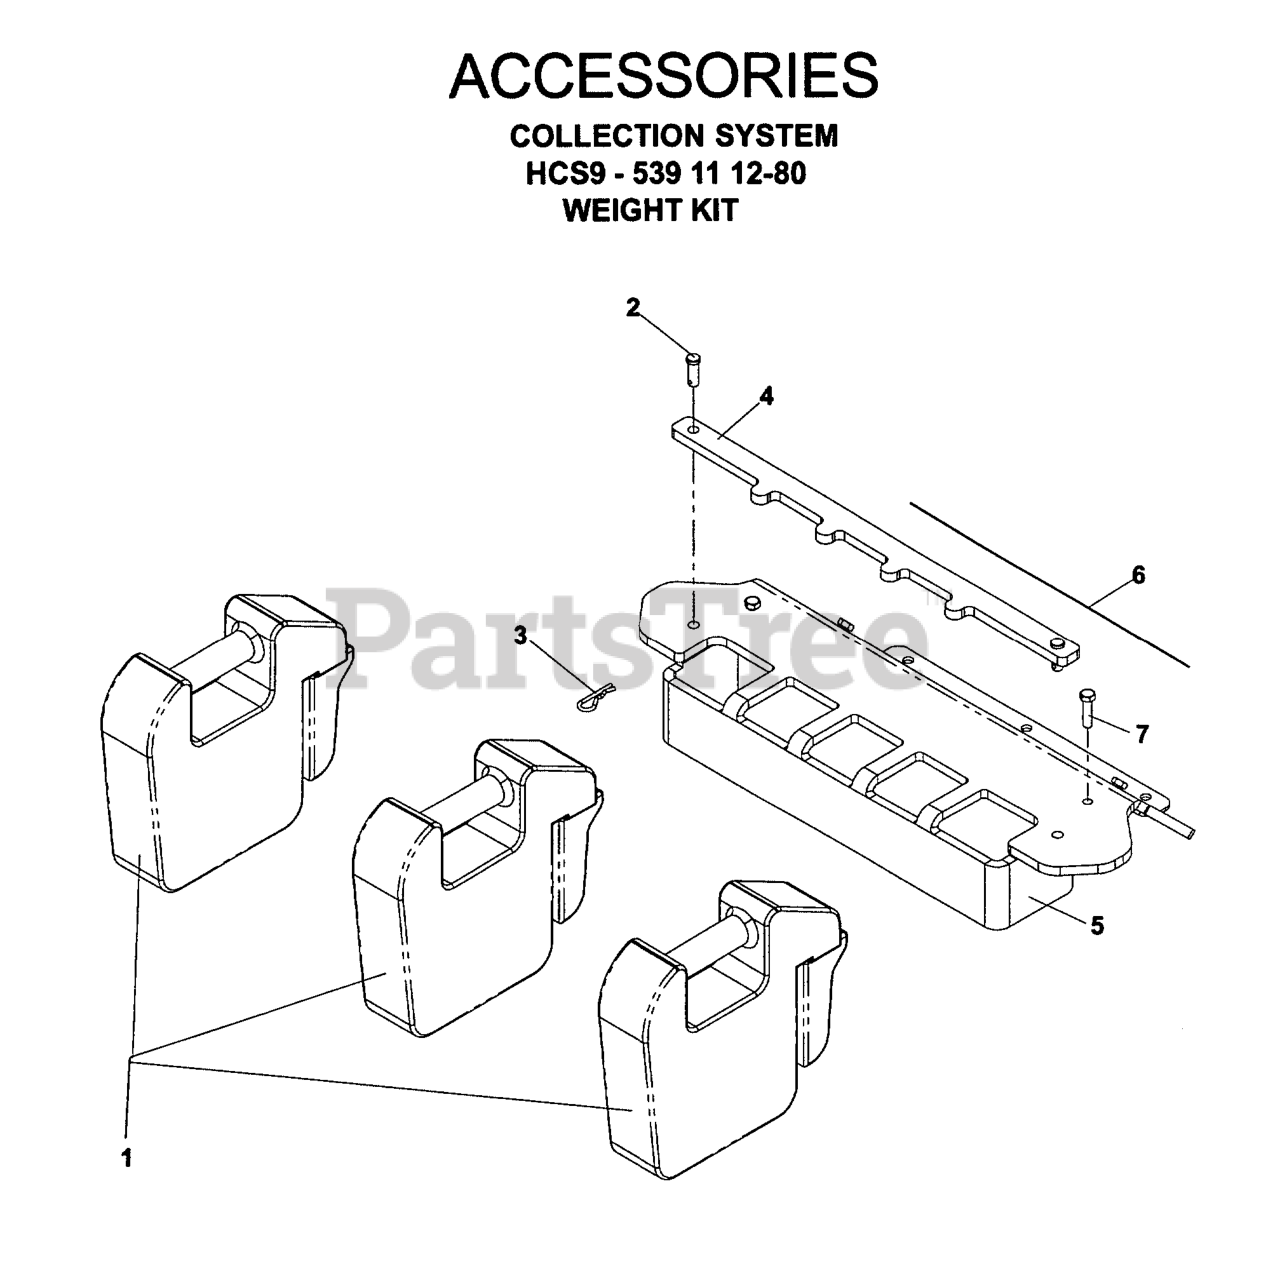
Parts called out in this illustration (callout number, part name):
1	FRT WEIGHT CAST PZ DFS
2	CLEVIS PIN
3	RETAINER SPRING
4	HOLD DOWN, WEIGHT BAR
5	WEIGHT BAR, IZ
6	ANTI-SKID PAD
7	HCS 5/16C X 1 1/4
